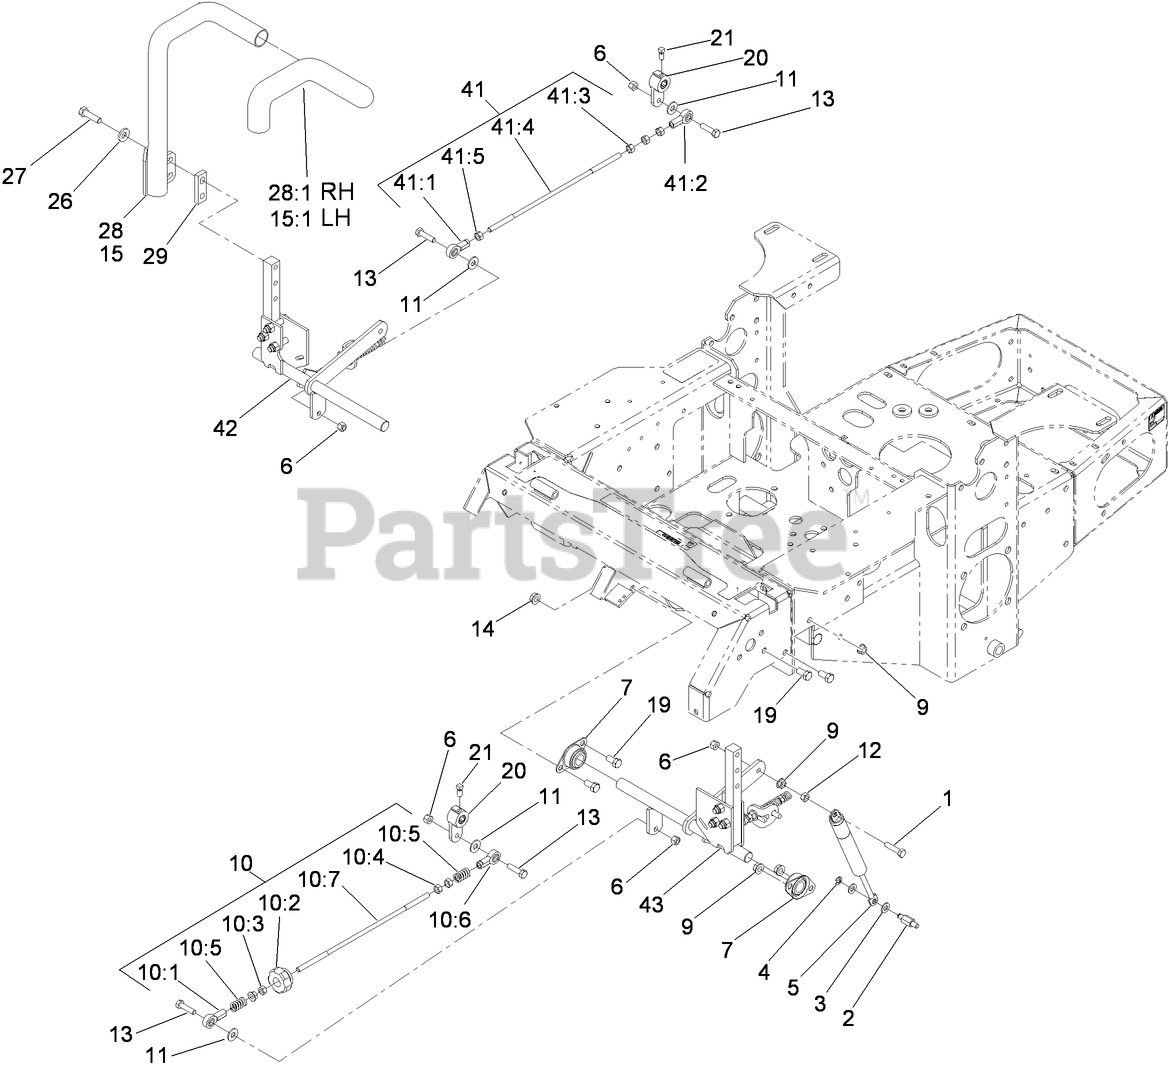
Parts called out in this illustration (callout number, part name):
1	SCREW-HH
2	PIN-DAMPER
3	WASHER-PLAIN
4	RING-RETAINING, EXT
5	DAMPER-CONTROL, MOTION
6	NUT-LOCK, NI
7	BEARING-FLANGE, SIDE
9	NUT-HF
10	TRACKING ROD ASM
10:1	BALLJOINT-RH
10:2	NUT-HEX
10:3	KNOB-TRACKING
10:5	SPRING-COMPRESSION
10:6	BALLJOINT-LH
10:7	Link-Rod, Tracking
11	WASHER-FLAT
12	NUT-HEX
13	SCREW-HH
14	NUT-HHF, WHIZ
15	LH LEVER ASM
15:1	Grip-Control, Motion
19	SCREW-HH
20	ARM-CONTROL
21	SCREW-SET
26	WASHER-BELLEVILLE
27	SCREW-HH
28	RH LEVER ASM
28:1	Grip-Control, Motion
29	SPACER, CONTROL LEVER
41	TRACKING ASM
41:1	BALLJOINT-RH
41:2	BALLJOINT-LH
41:4	Link-Rod, Tracking
41:5	NUT-HEX
42	RH MOTION CONTROL ASM
43	LH MOTION CONTROL ASM
